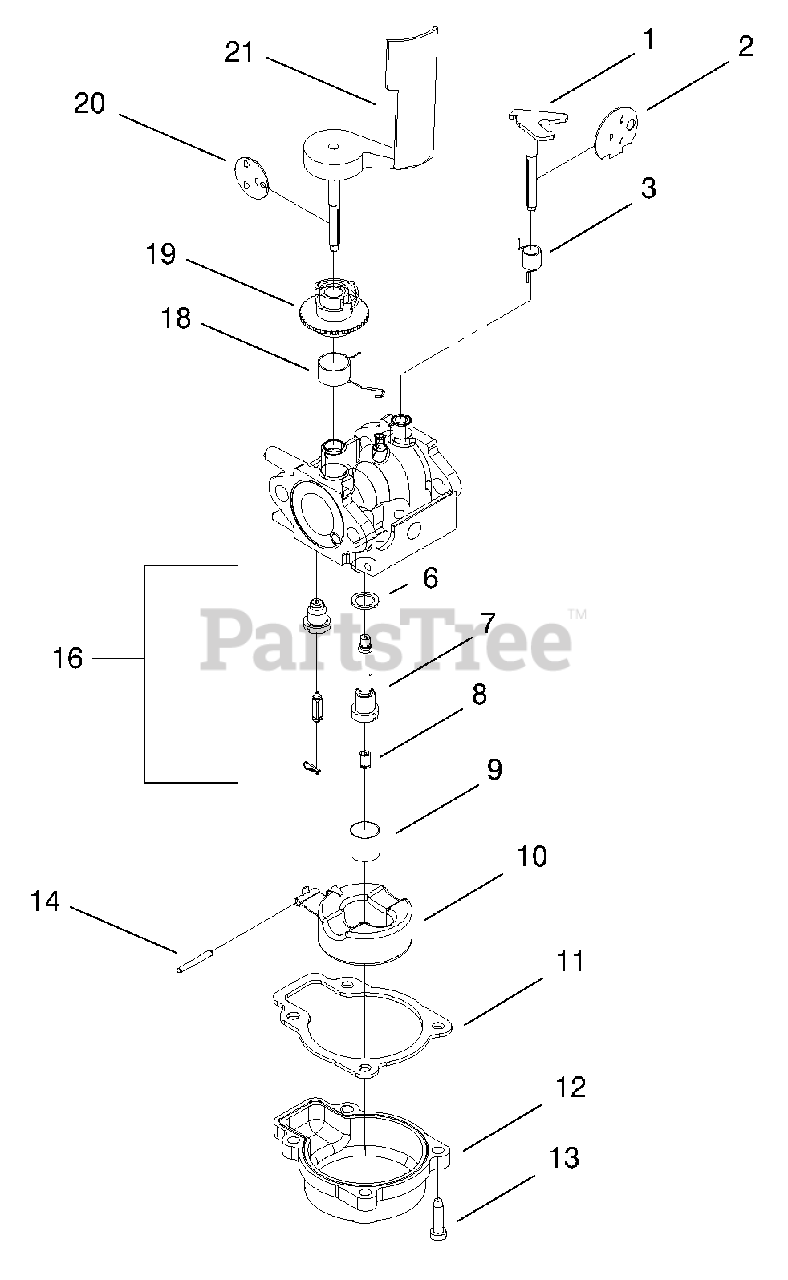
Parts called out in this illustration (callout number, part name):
1	Shaft-Choke
2	Disc-Choke
3	Spring-Choke
8	Jet-Main 77.5
9	Filter-Fuel
10	Float&arm Ay
12	Chamber-Float
13	Screw-HH
16	Val/Seat-Float
18	Spring-Gov.
19	Airvane-Collar
20	Disc-Throttle
21	Air Vane&shaft
